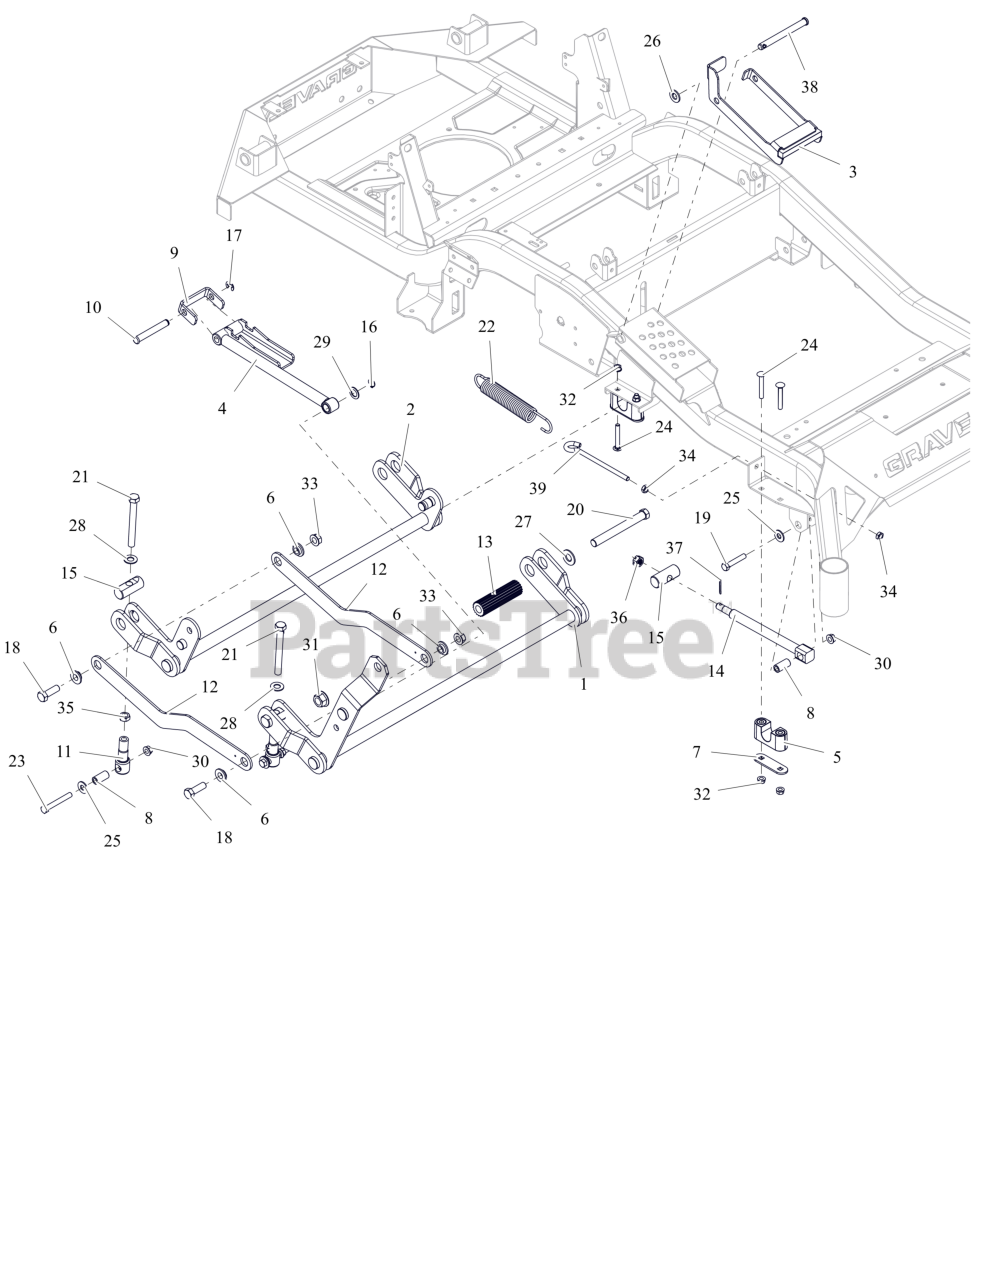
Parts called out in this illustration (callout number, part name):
1	WLDMT, FRONT DECK LIFT PIVOT
2	WLDMT, REAR DECK LIFT PIVOT
3	WLDMT, HOC TRANSFER LOCK (BLACK)
4	WLDMT, HOC LIFT ARM (BLACK)
5	ASM-BUSHING, DECK LIFT
6	BSHG-FLG .515X.750X.310X1.120
7	PLATE, BEARING SUPPORT
8	SPACER, DECK LEVELING
9	BRKT, HOC LINE
10	PIN, .499/.494 x 3.385 CLEVIS
11	LINK, DECK LIFT FORMED
12	LINK, DECK
13	ROD, FOOT PEDAL (BLACK)
14	DRAG,LINK-HD
15	PIN, DECK LIFT
16	RG-RTNG-EXT .625X.050
17	RG-RTNG-EXT .500X.042 (E)
18	BLT,HEX .50-13X1.50 G5 ZCC
19	BLT,HEX .38-16X2.00 G5 ZCC
20	BLT, HEX .62-11X5.50 G5 FBP
21	BLT, HEX .50-13X4.50F G8 ZCC
22	SG-TENS .162X1.25X8.25 WLD 25
23	BLT, HEX .38-16X2.75 G8 ZCC
24	BLT, RHSSN.31-18X2.25 G5 ZCC
25	WSHR,FLT .438X1.00X.083 ZCC
26	WSHR,FLT .531X1.062X.095 ZCC
27	WSHRFLT 5/8SAE CARBHARD FBP
28	WSHR, FLT .557X1.040X.102 ZCC
29	WSHR, FLT .630X1.005X.062 ZCC
30	NUT-LK-TOP-FLG .38-16 ZC120
31	NUT,FLG-TOP LK .625-11 FBP
32	NUT,LK-CTR-FLG .31-18 GF ZCC
33	NUT-LK-TOP-FLG .500-13 GF ZCC
34	NUT-JAM .375-16 G2 ZCC
35	NUT-JAM .500-13 G2 ZCC
36	NUT-SL .50-13
37	PIN,CTR.12X1.25EXTPRSQCT ZC120
38	PIN, SLIC-.500X4.97X4.55 -ZC
39	BOLT,.38-16 X 5.25-.62 DIA EYE
